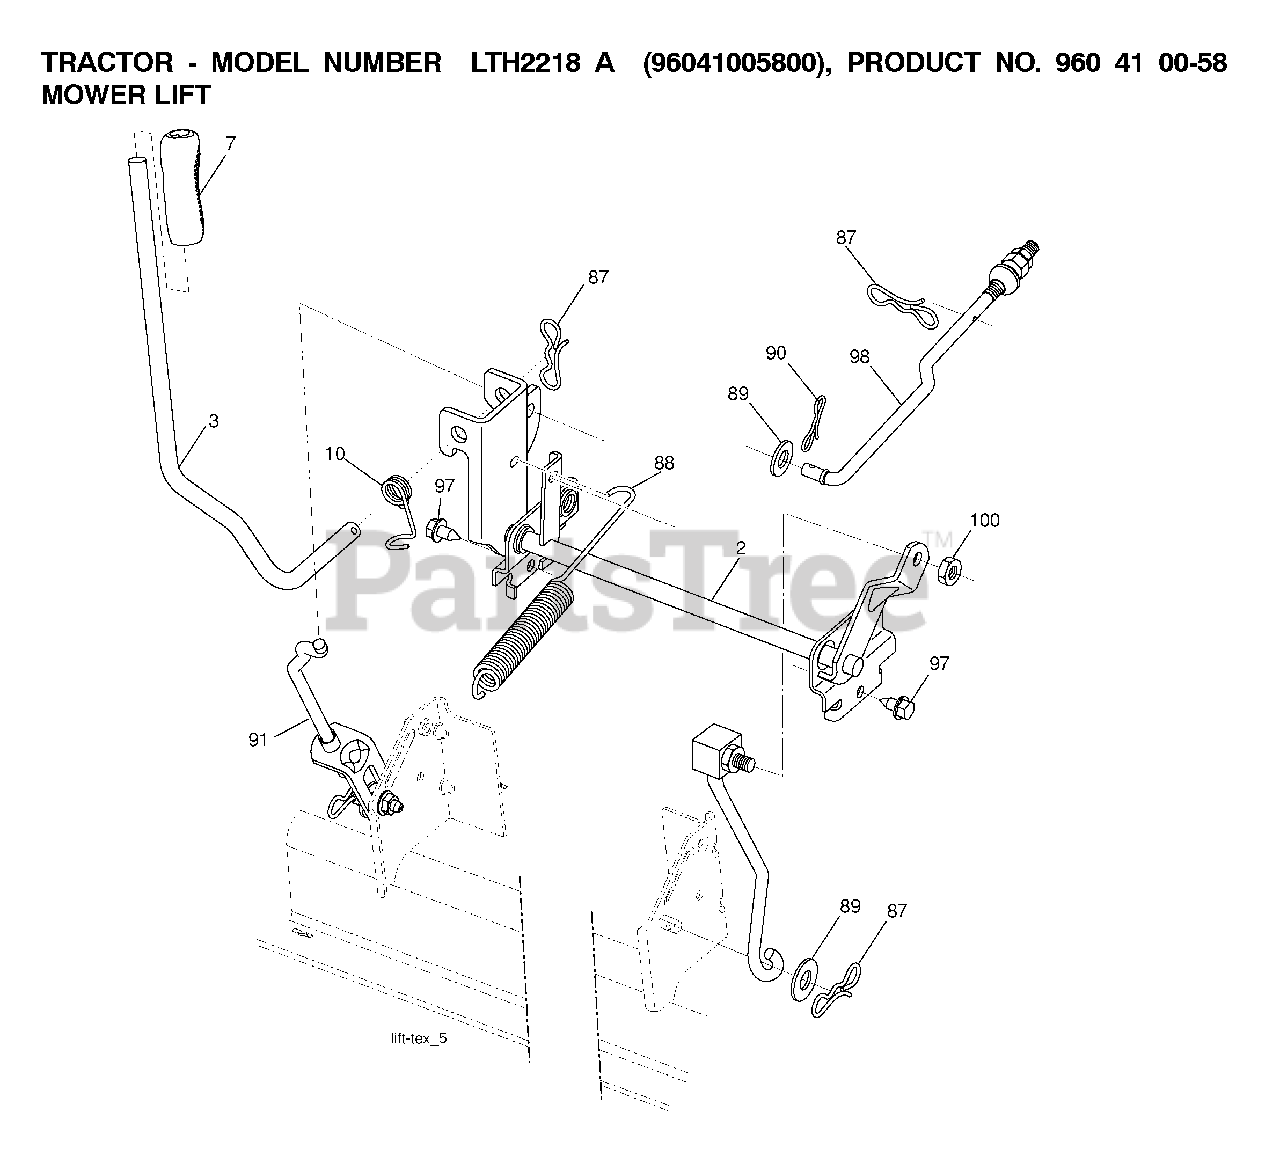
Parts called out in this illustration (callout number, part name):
2	SHAFT.ASM.LIFT.CROSS.H
3	LEVER.LIFT.HANDLE.LT
7	GRIP.HANDLE.LIFT.PVC.BLACK
10	SPRING.TORSION.LIFT.HANDLE
87	PIN.COTTER.7/16.BOW TI
88	SPRING.LIFT.ASSIST
89	WASHER.CLEAR.ZINC
90	PIN.COTTER.5/16.BOW TI
91	LINK.ASM.LIFT.REAR
97	SCREW, 3/8-16X3/4
98	LINK.ASM.SUSP.FRONT.MW
100	LOCKNUT
